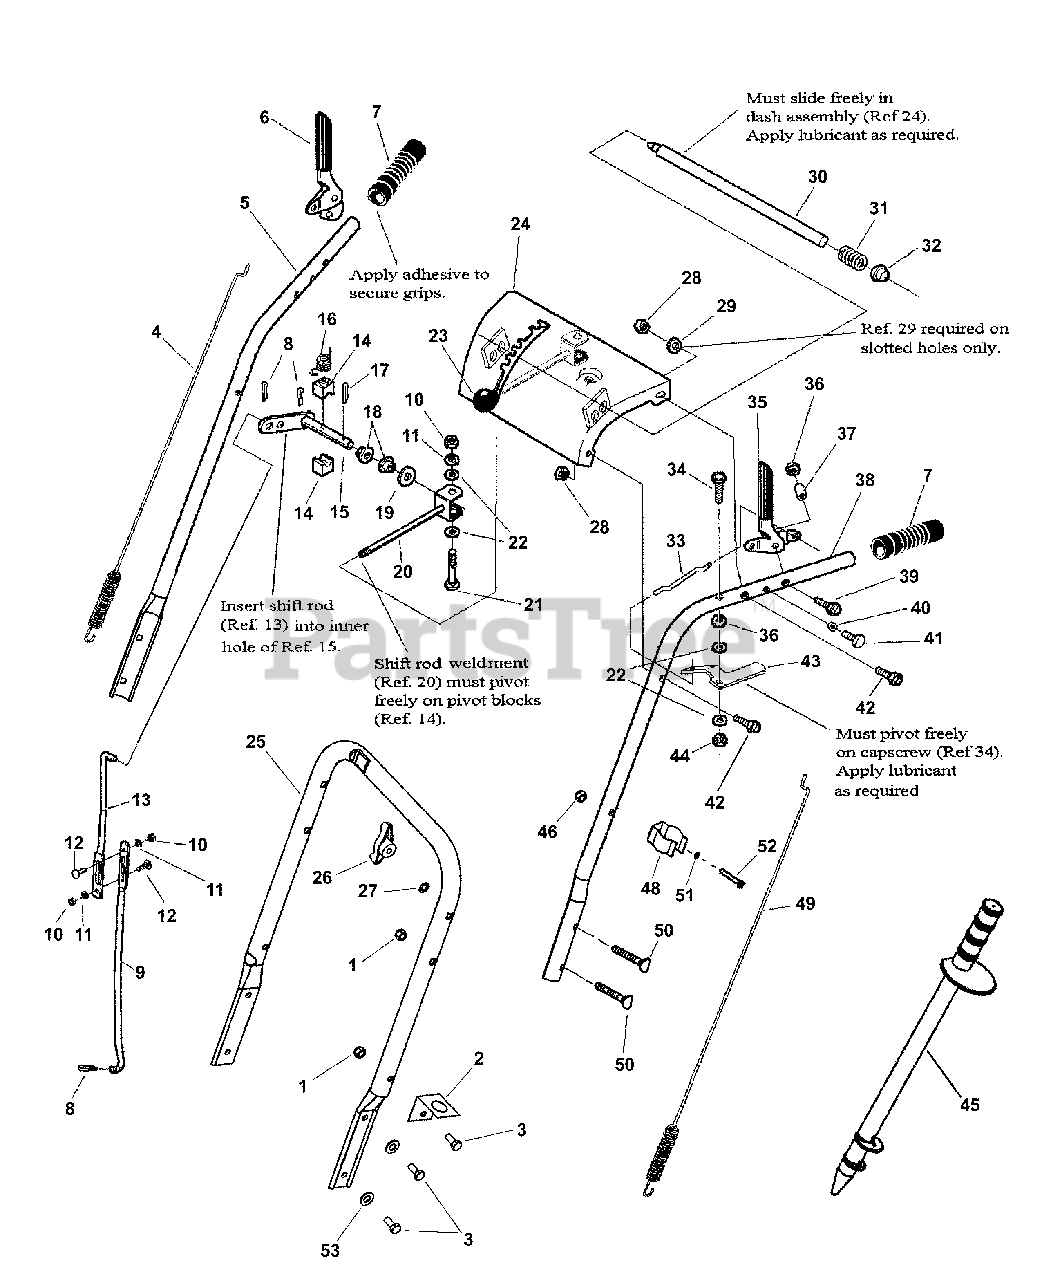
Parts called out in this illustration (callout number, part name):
1	NUT, 5/16-18 Hex Nyloc
2	BRACKET, Snow Stick- Lower
3	SCREW, 5/16-18 x 3/4" Hex Head Cap
4	CLUTCH CABLE, Auger Drive- RH
5	HANDLE, Upper, Right Hand
6	GRIP, Clutch, RH
7	GRIP, Foam, Black
8	HAIR PIN
9	ROD, Shift, Lower
10	NUT, 1/4-20 2B Hex
11	LOCKWASHER, 1/4" Spring
12	BOLT, 1/4-20 x 2" Short Square Neck Carriage, GR 5
13	ROD, Upper, Shift
14	BLOCK, Pivot
15	WELDMENT, Shift Rod Pivot
16	SPRING, Compression
17	COTTER PIN, .125 x 1.00
18	BUSHING, .500 ID x .750 OD x .25
19	WASHER, 1/2" Flat (.531 ID x 1.250 OD x .08 Thick)
20	WELDMENT, Shift Rod
21	SCREW, 1/4-20 x 2-1/4" Hex Flange Lock
22	WASHER, .250 (.27 ID x .62 OD)
23	KNOB, Tapered - 3/8-16 Internal Thread- Red
24	WELDMENT, Dash
25	HANDLE, Lower
26	WING KNOB, 5/16-18
27	WASHER, 5/16" Internal Tooth Lock
28	NUT, 5/16-18 Hex Flange Nyloc
29	WASHER, .312 (.34 ID x .75 OD)
30	ASSEMBLY, Rod w/Pin
31	SPRING, Compression
32	PUSH NUT
33	ROD, Hold Down
34	SCREW, 1/4-20 x 2" Hex Head Cap, GR 5
35	GRIP, Clutch, LH
36	NUT, 1/4-20 Hex Centerlock
37	SPACER, Handle
38	HANDLE, Upper, Left Hand
39	SCREW, 1/4-20 x 1-1/2" Hex Head Cap
40	SPACER, .268 ID x .394 x .165
41	SCREW, 1/4-20 x 3/4" Pan Head Torx Self-Tap
42	SCREW, 5/16-18 x 1-1/2" Hex Head Cap, GR 5
43	LEVER, Pivot
44	NUT, 1/4-20 Hex Nyloc
45	SNOW STICK
46	NUT, #10-24 Hex Center Lock
48	HOLDER, Snostik- Upper
49	CLUTCH CABLE, Ground Drive- LH
50	BOLT, 5/16-18 x 2" Curved Head Square Neck GR 2
51	WASHER, #10 Internal Tooth Lock
52	SCREW, #10-24 x 2" Hex Washer Head Machine, GR 5
53	LOCKWASHER, Spring .312
